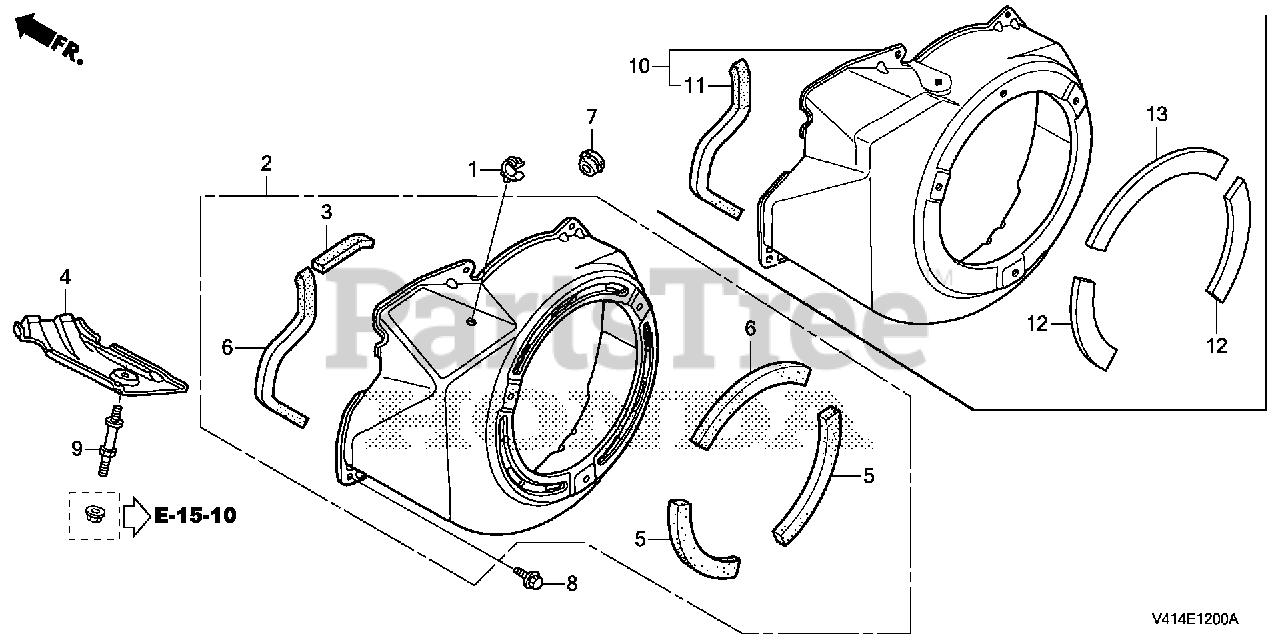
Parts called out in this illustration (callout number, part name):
1	CLIP, TUBE
2	COVER, FAN *R280* (POWER RED)
3	SEAL, FAN COVER
5	SEAL, RECOIL
6	SEAL, RECOIL
7	GROMMET, DRAIN HOLE
8	BOLT, FLANGE (6X12) (CT200)
9	BOLT, SHROUD (LOWER)
